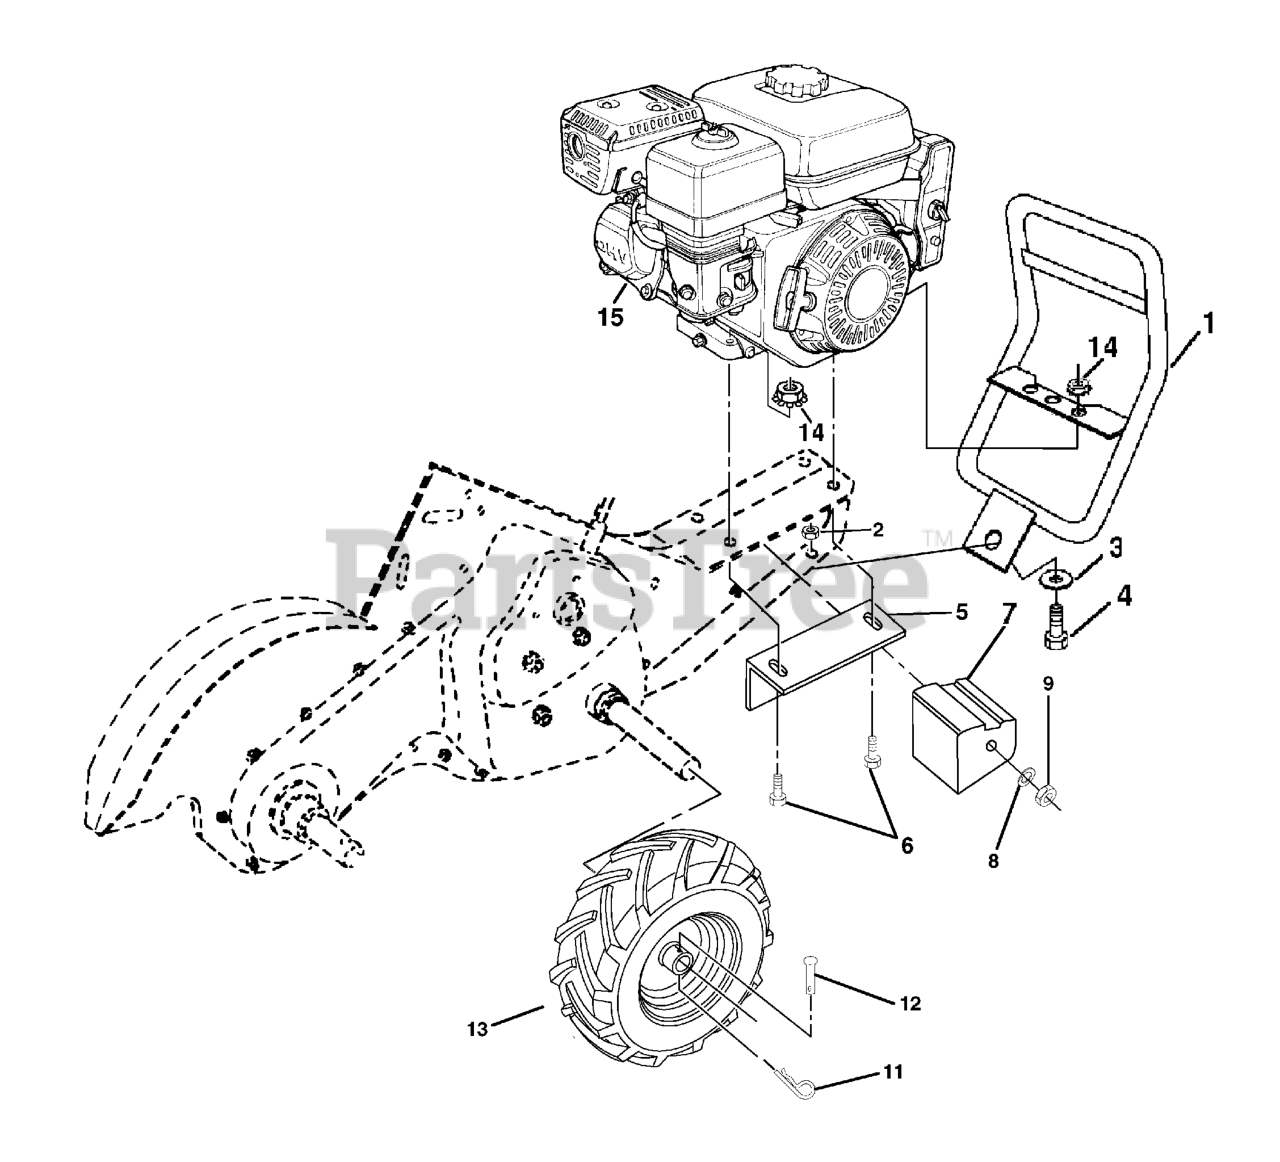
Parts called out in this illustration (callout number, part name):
1	BUMPER
2	LOCKNUT-FLANGE 5/16-18
3	WASHER
4	BOLT
5	DNO BRACKET RH CRT
6	BOLT
7	COUNTERWEIGHT, RH
8	WASHER, LOCK 3/8
9	NUT.HEX.3/8-16UNC
11	RETAINER M
12	RIVET,DRILLED
13	TIRE.16X4-8.CHEVRON.TILLER
13	RIM
13	VALVE STEM LT
14	NUT
15	Engine, Honda
